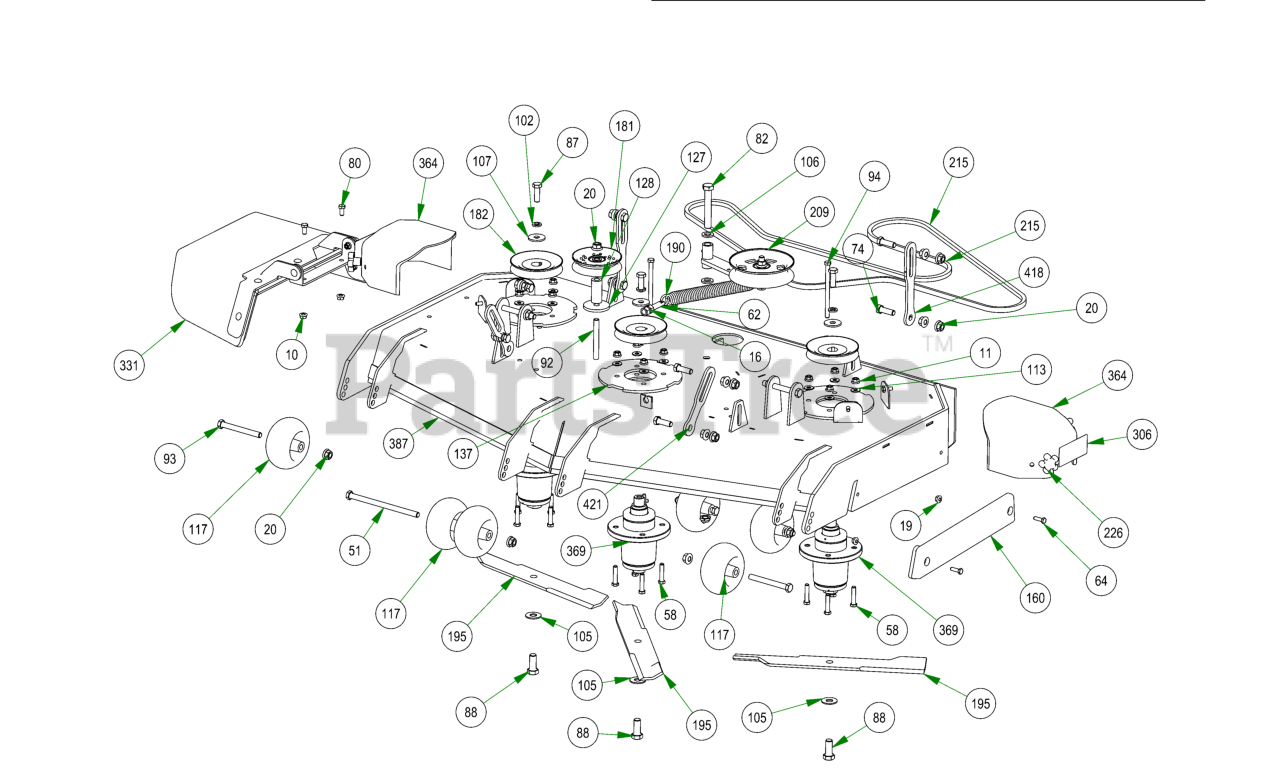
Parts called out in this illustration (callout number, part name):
10	3/8-16 HEX SERRATED FLANGE NUT HARD/ZINC
11	3/8-16 NYLON INSERT FLANGE LOCKNUT (GR.F) ZINC
13	5/8-11 NYLON INSERT JAM LOCKNUT ZINC
16	1/2-13 HEX NUT ZINC
19	5/16-18 NYLON INSERT FLANGE LOCKNUT ZINC
20	1/2-13 NYLON INSERT FLANGE LOCKNUT ZINC
51	1/2-13 X 8 HEX CAP SCREW GR 5 ZINC
58	3/8-16 X 1-3/4 HEX C/S (GR.5) ZC
62	All Thread
64	5/16-18 X 1 HEX CAP SCREW (GR.5) ZINC
74	1/2-13 X 1-1/2 HEX CAP SCREW (GR.5) ZINC
75	1/2-13 X 4 HEX CAP SCREW (GR.8) ZINC YELLOW
80	3/8-16 X 3/4 HEX CAP SCREW (GR.5) ZINC
82	5/8-11 X 4 HEX CAP SCREW (GR.8) ZINC YELLOW
87	1/2-20 X 1-1/2 HEX CAP SCREW (GR.5) ZINC
88	5/8-18 X 1-1/2 HEX CAP SCREW (GR.8) ZINC YELLOW
92	1/2-13 X 4-1/4 HEX CAP SCREW (GR.5) ZINC
93	1/2-13 X 4-1/2 HEX CAP SCREW (GR.5) ZINC
94	3/8-16 X 5-1/2 HEX CAP SCREW (GR.5) ZINC
98	5/16-18 X 1 CARRIAGE BOLT (GR.8) ZINC
102	1/2 SPLIT LOCKWASHER (GR.8) ZINC/YELLOW
105	5/8 USS FLAT WASHER (1-3/4" OD) GR.8 ZINC YELLOW
106	.635 ID X 1.120 OD X .140 THICK FLAT WASHER NYLON
107	1/2 BELLEVILLE WASHER (1-5/8 OD X .140 THK) ZINC
110	.360 ID X .983 OD X .120 THICK FLAT WASHER NYLON BLACK
113	5/16 USS FLAT WASHER (7/8 OD) ZINC
117	2019 Deck Wheel
127	MZ Deck Idler Spacer
128	2019 Revolt Stationary Idle Spacer
137	Deck Spindle Support Plate
160	REVISED TRIM BUMPER_20180226
163	5/16-24 X 1/4 SOCKET SET SCREW (CUP PT) PLAIN
181	4 3/4 Idler Pulley - ABFI-76
182	5" Spindle Deck Pulley
190	2019 Outlaw Gen2 Deck Spring
195	54" Fusion Blade for ZT/Mav/Outlaw/Revolt
209	2019 Revolt Deck Idler Assembly
215	42 inch Deck Belt- B120
223	1/4 X 1 SQ MACHINERY KEY 1018 STL PLN
226	5/16" Knob
229	Turnbuckle
246	1.02 ID X 1.38 OD X .250 THK SPACER ZINC
303	2018 54" Deck Decal
306	Danger Decal-Spindle/Discharge
313	2019 Revolt Deck Belt Route Decal
326	Deck Impact Patent Decal 9591803
331	2019 Outlaw Gen2 Chute Assembly
364	2023 Revolt pulley cover
365	R Series Rubber For Deck
366	61 Bolt in Baffle Deck v2 Stripping Plate
369	OUTLAW SPINDLE ASSEMBLY
387	2023 54'' DECK
418	2023 Stand-On Rear Deck HangerV2
421	Deck Hangar
